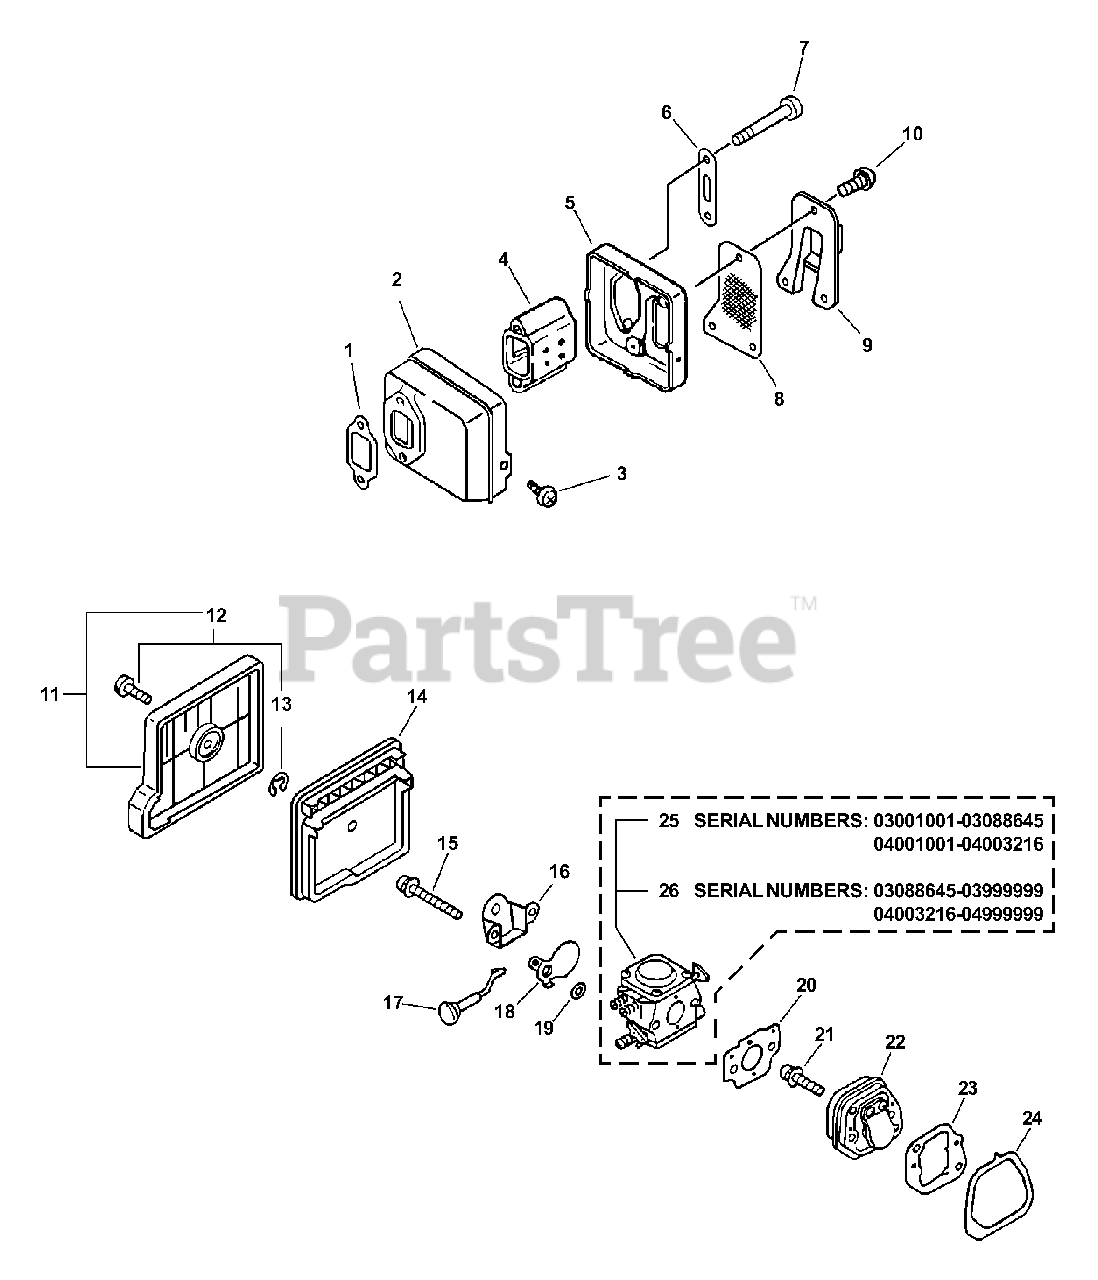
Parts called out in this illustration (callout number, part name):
1	GASKET, MUFFLER
3	SCREW TAPPING 4×8
4	SILENCER
5	COVER, MUFFLER
6	PLATE, EYE
7	BOLT 6 MM
8	SCREEN, SPARK ARRESTER
9	COVER, MUFFLER
10	SCREW TAPPING 4×8
11	COVER ASSY, AIR FILTER
12	THUMBSCREW
13	E-RING 4
14	FILTER, AIR
15	SCREW 5×45
16	PLATE, PREVENT
17	ROD, CHOKE
18	SHUTTER, CHOKE
19	WASHER 5.5×8×0.8
20	GASKET, INTAKE
21	SCREW 5×18
22	INSULATOR KIT
23	GASKET, INTAKE
24	SEAL, INTAKE
25	CARBURETOR - WT-589
26	CARBURETOR - WT-589
